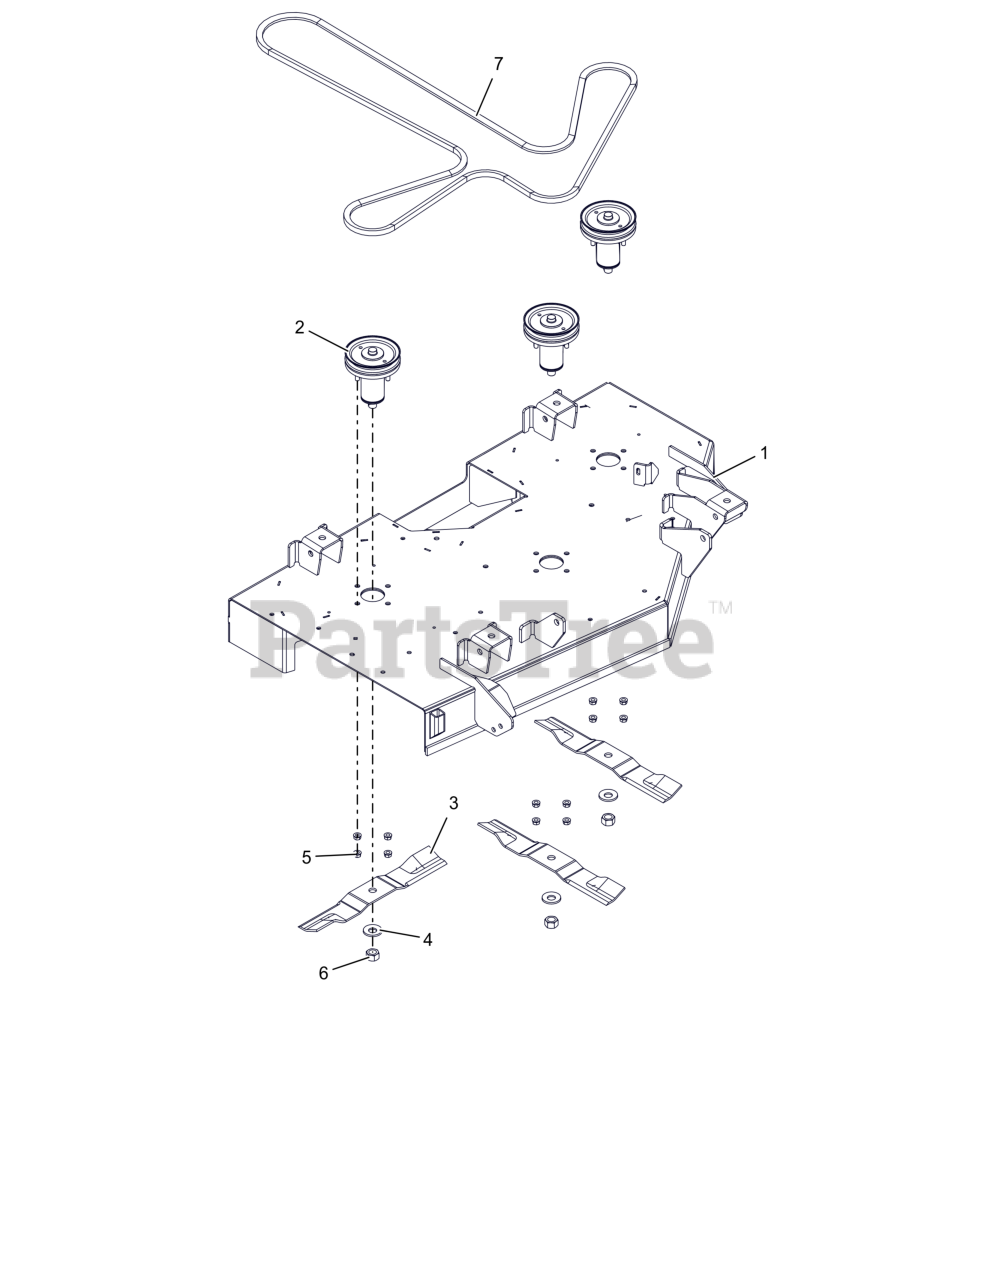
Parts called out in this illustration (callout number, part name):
1	KIT, 42" ARIENS DECK W/DECALS
2	KIT- DECK SPINDLE ASSM- 42"
3	BLADE, MOWER 15.00"
4	WSHR-BLVL .669X1.535X.138
5	NUT,LK-CTR-FLG .31-18 GF ZCC
6	NUT-STD .625-18 ZCC
7	V-BELT, 4L-WRAPPED
